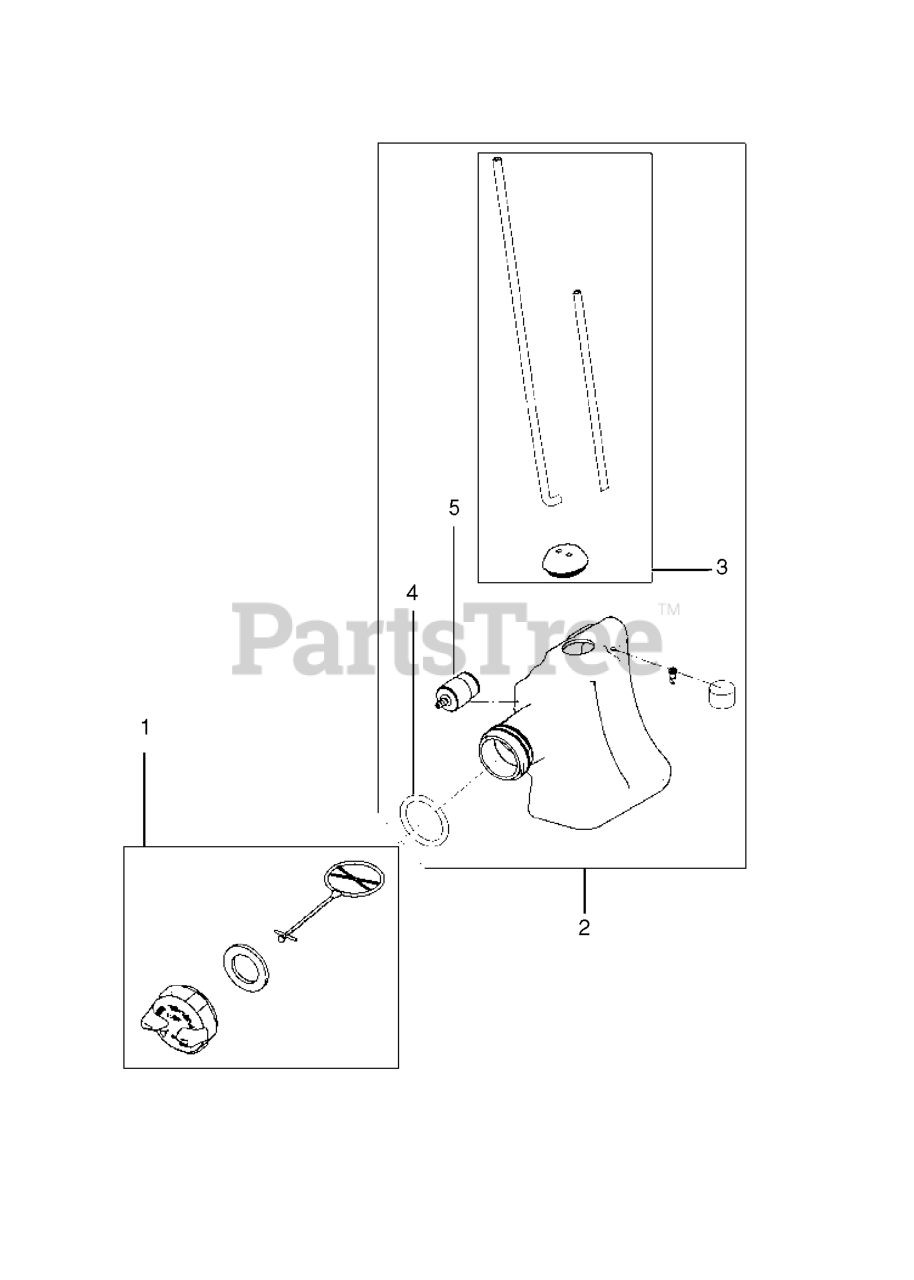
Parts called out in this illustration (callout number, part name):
1	HANDLE.UPPER.3.POS.BS.AW2.GREY
2	CABLE.BBC.22+.AW2.BS.ERGO.WALK
6	KNOB.HANDLE.PLASTIC.STAR.BLACK
8	BAIL.ARM ASM.ERGO OM.ORG/BLK
9	DOOR.REAR.ASM.22+GEN.FG/RG.498
11	E-RING.12MM.SHAFT
16	NUT
17	BAFFLE.REAR.22+RGD.AWD.PLASTIC
18	T-KNOB.NEW ROPE GUIDE
19	GUIDE.ROPE.BLK.ZINC.CHROM
20	SKIRT.REAR.22+RGD.HIGH WHEEL
21	SPRING.LH.BLACK
24	SPRING.RH.GRAY
26	SCREW,DOOR/HANDLE.PIVOT
28	BOLT.CARRIAGE.LN.5/16-18X.5/8
30	GBAG.BA85028EM.NOFRAME.GRY/SLV
31	FRAME.GBAG.22+.BLK
32	LATCH.DOOR.ZINC
33	DOOR.MULCH.22 PLUS.HUSQ.GREY
36	BRACKET.ASM.HINGE.21.FWGD.
38	DEFLECTOR.CLIPPING.22.BLACK
39	BRACKET.ASM.HANDLE.LT.22+.498
40	BRACKET.ASM.HANDLE.RT.22+.498
41	BOLT 3/8-16X1-1/8
42	SPRING.TORSION
43	NUT.FLANGE.1-4-20-SERR
44	KIT.HSG.22+AW.MC.WO.BBC.STB
45	ROD.HINGE.21
46	PULLEY.BBC.DRIVING
47	BLADE.22.REAPER.BBC.RUST PREVE
48	WASHER.CRANK.BOLT
49	LOCKWASHER
50	BOLT.BLADE
51	BAFFLE.FRONT.22.PLUS
52	DANGER DECAL
53	BOLT.5/16HEX.WHS.HD
56	SCREW.HX.13X.750
57	NUT.FLANGE.5/16
58	HANDLE.LOWER.22+EZS.498
59	BOLT, HANDLE 5/16-18X1.75
60	E-RING.12MM.SHAFT
61	BOLT.BBC.TENSION.PIVOT
83	TAPPING SCREW
84	FASTENER.PUSH.O.250X0.783
85	BRACKET.SKIRT.22+.BZP
96	CLIP.CABLE.BLK
99	COVER.ASSEMBLY.FRONT.22+AWD
100	CONTROL.THROTTLE.BBC.HON.22+AW
103	SPRING.BRAKE.RESET
107	BELT.COG.BBC
108	SCREW, HEX HD 3/8-24 X 1-3/8
109	HUB.FREE.BBC.ASSEMBLY(2 2MC)
110	ARM.BBC.TNSION.ARM.PULL(2 2MC)
112	BRACKET.CABLE MOUNTING.22+
113	NUT.FLANGE.1-4-20-SERR
114	BUMPER.LEFT SIDE 22+.498
115	SCREW.HI-LO. 5/16 X 1.00
117	BOLT.HEX.HD.WASHER.5/16-18X.75
118	COVER.INSIDE.LOWER.LT.EZS
119	BOLT.PAWL.M6
120	PAWL.ADJUSTMENT.EZS.LEFT
121	BRACKET.BAG.ASM.EZS.LH.BLK
122	NUT.PAWL.M6
123	SPRING.TORSION.PAWL ENG.LT
124	COVER.OUTSIDE.LOWER.EZS.LT
125	SCREW.TORX.PAN HEAD.M6-1
126	CABLE.EBA.ACTUATION.LT.BBC.MOW
127	DOOR.REAR.LIFT.ASM EZS
128	E-RING.5/32.HD
129	CABLE.EBA.ACTUA.RT.BBC.ERGOHD
130	SCREW.PAN.HEAD.#10
